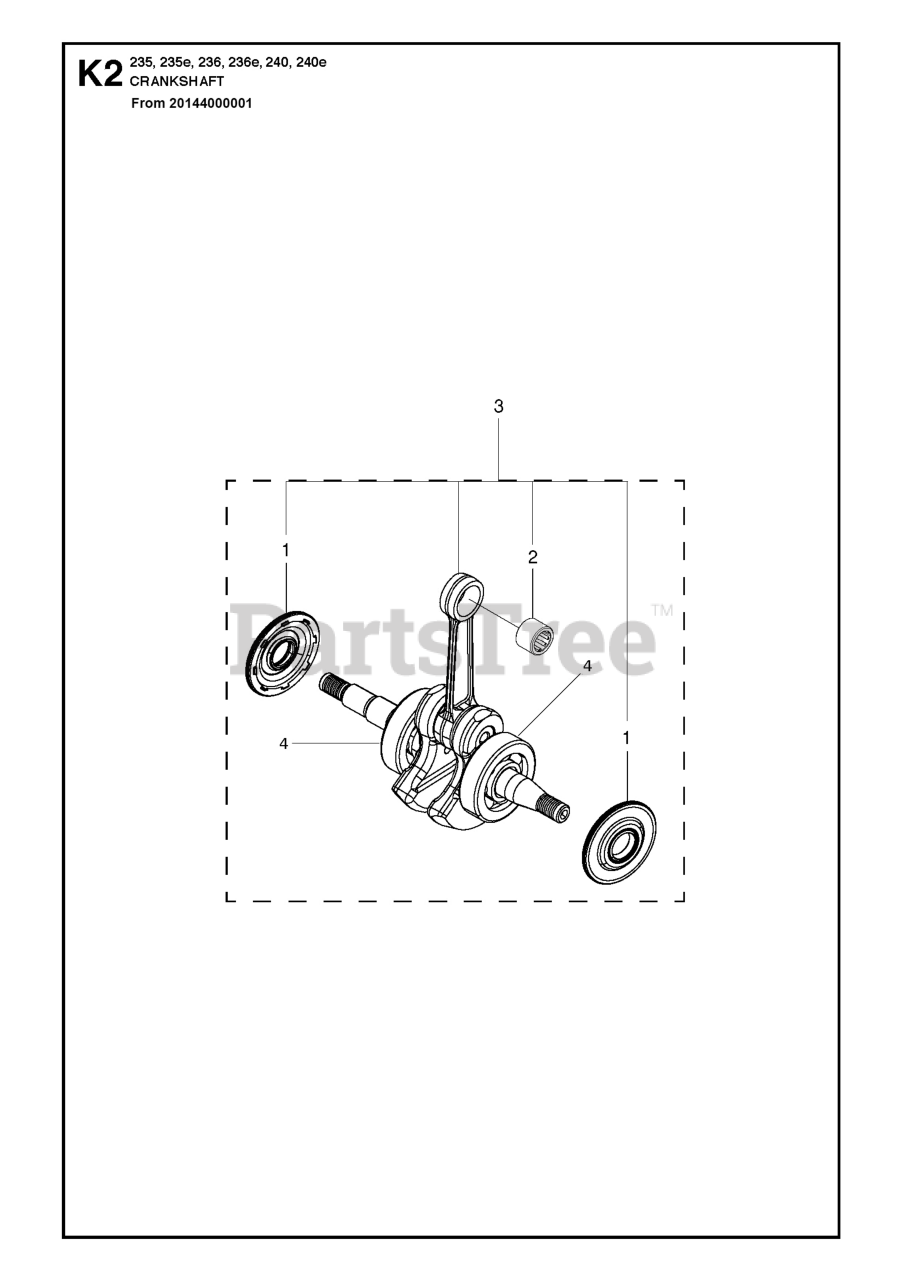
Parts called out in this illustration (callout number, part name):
1	SEAL RADIAL BEARING
2	CRANKSHAFT COMPLETE
3	Crankshafts
